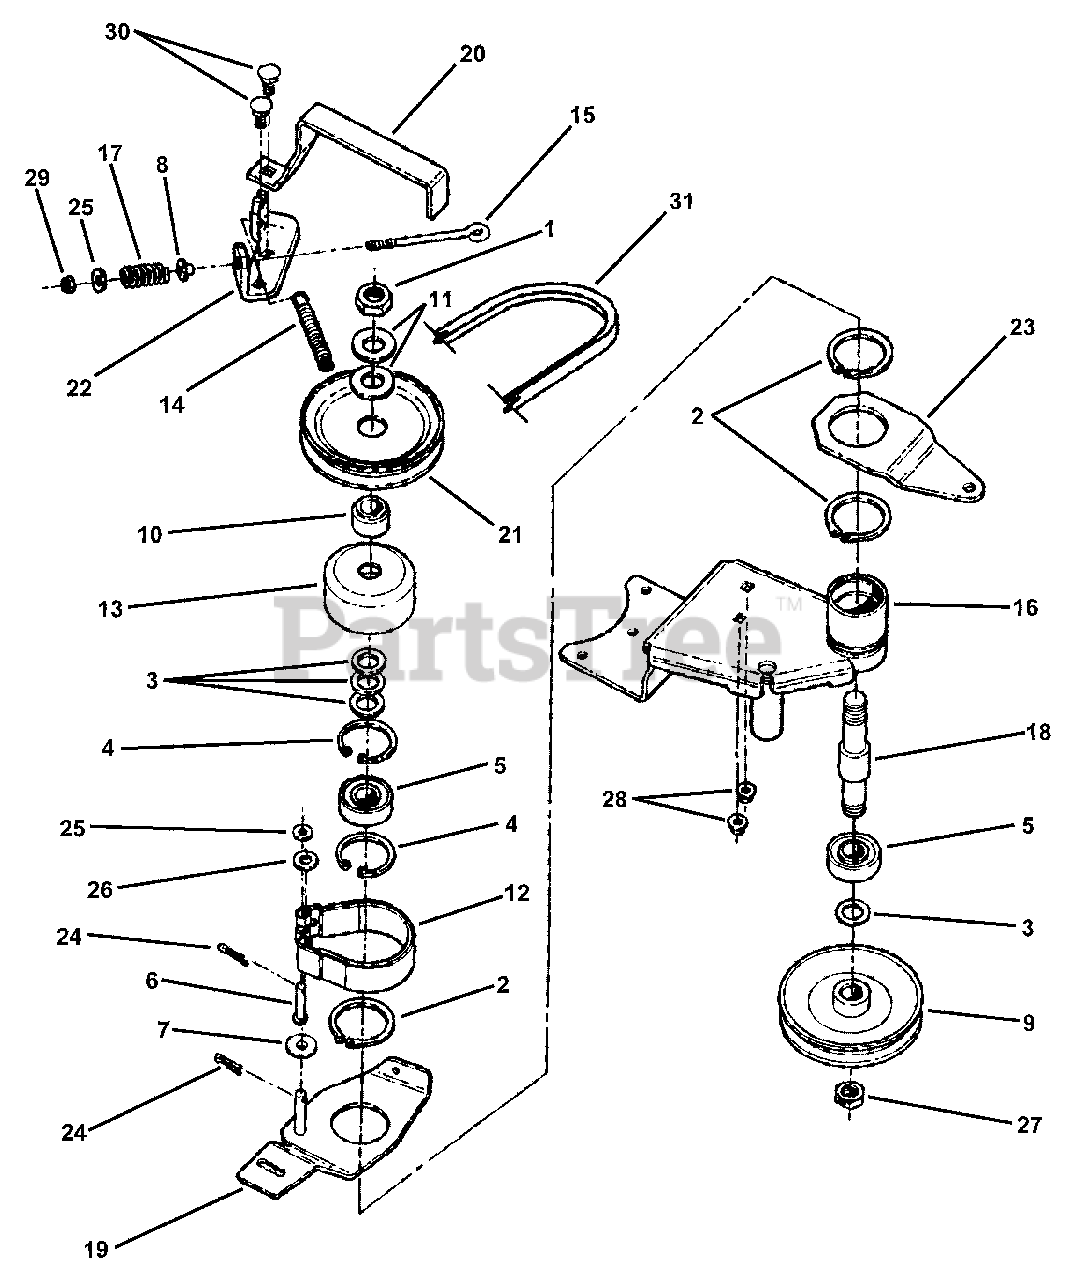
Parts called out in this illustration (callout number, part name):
1	NUT, 3/4-16 Hex Flange Jam, Grade 8
2	RING, 2" External Retaining
3	WASHER, 3/4" I.D. x 1-1/8" O.D. x 1/16" Thick Flat
4	RING, 1.75 External Retaining
5	BEARING, Spindle
6	WELD PIN, .37 x 2"
7	SPACER, .31 I.D. x .39 O.D. x 1" Nylon
8	BUSHING, .27 I.D. x .35 O.D. x .4 Flanged
9	PULLEY, 5.0 O.D.
10	PULLEY HUB, PM
11	WASHER, 3/4" I.D. x 1-1/2" O.D. x 1/16" Flat
12	BAND, Brake
13	DRUM, 17mm Brake
14	SPRING
15	EYE-BOLT, 1/4-20 Thread
16	WELDMENT, Spindle Bracket/Housing
17	SPRING, Rectangle Wire Die
18	SPINDLE, Center
19	WELDMENT, Idler Arm
20	BELT GUIDE, Front
21	PULLEY, Jack Shaft
22	BRACKET, Brake Cable
23	IDLER ARM
24	PIN, 3/32 x 3/4" Cotter
25	WASHER, 1/4" Flat
26	WASHER, 3/8" SAE Flat
27	NUT, 5/8-18 Hex Center Lock Jam
28	NUT, 5/16-18 Hex Flange Lock
29	NUT, 1/4-20 Hex Top Lock
30	BOLT, 5/16-18 x 1" Short Neck Carriage, Grade 5
31	BELT, Engine to Deck
